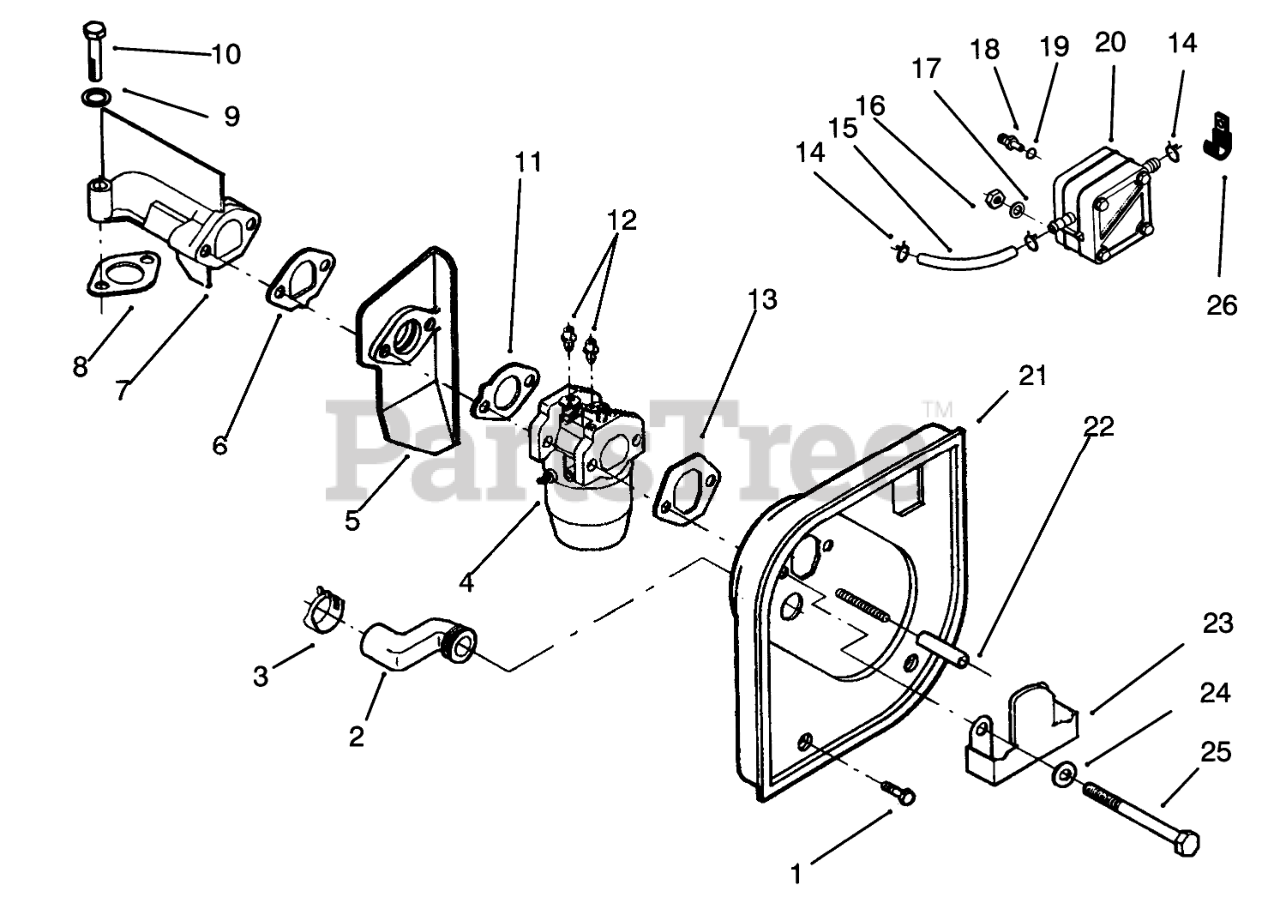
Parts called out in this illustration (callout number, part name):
1	SCREW-HWH
2	BREATHER TUBE
3	CLAMP-HOSE
4	CARBURETOR
5	CARB INSULATOR
6	Gasket-Insulator
7	INTAKE ELBOW
8	Gasket-Intake
9	WASHER-FLAT (M8)
10	SCR-HHC (M8X50)
11	Gasket-Insulator
12	LINK CLIP
13	A/C GASKET
14	CLAMP-HOSE
15	FUEL HOSE
16	HEX NUT
17	WASHER-LOCK
18	FUEL PUMP SPUD
19	FUEL PUMP GROMMET
20	FUEL PUMP
21	AIR CLEANER PAN ASM
22	AIR CLEANER SPCR SEAL
23	AIR DEFLECTOR PLATE
24	WASHER-FLAT
25	THREAD FORM SCREW
26	Clip
